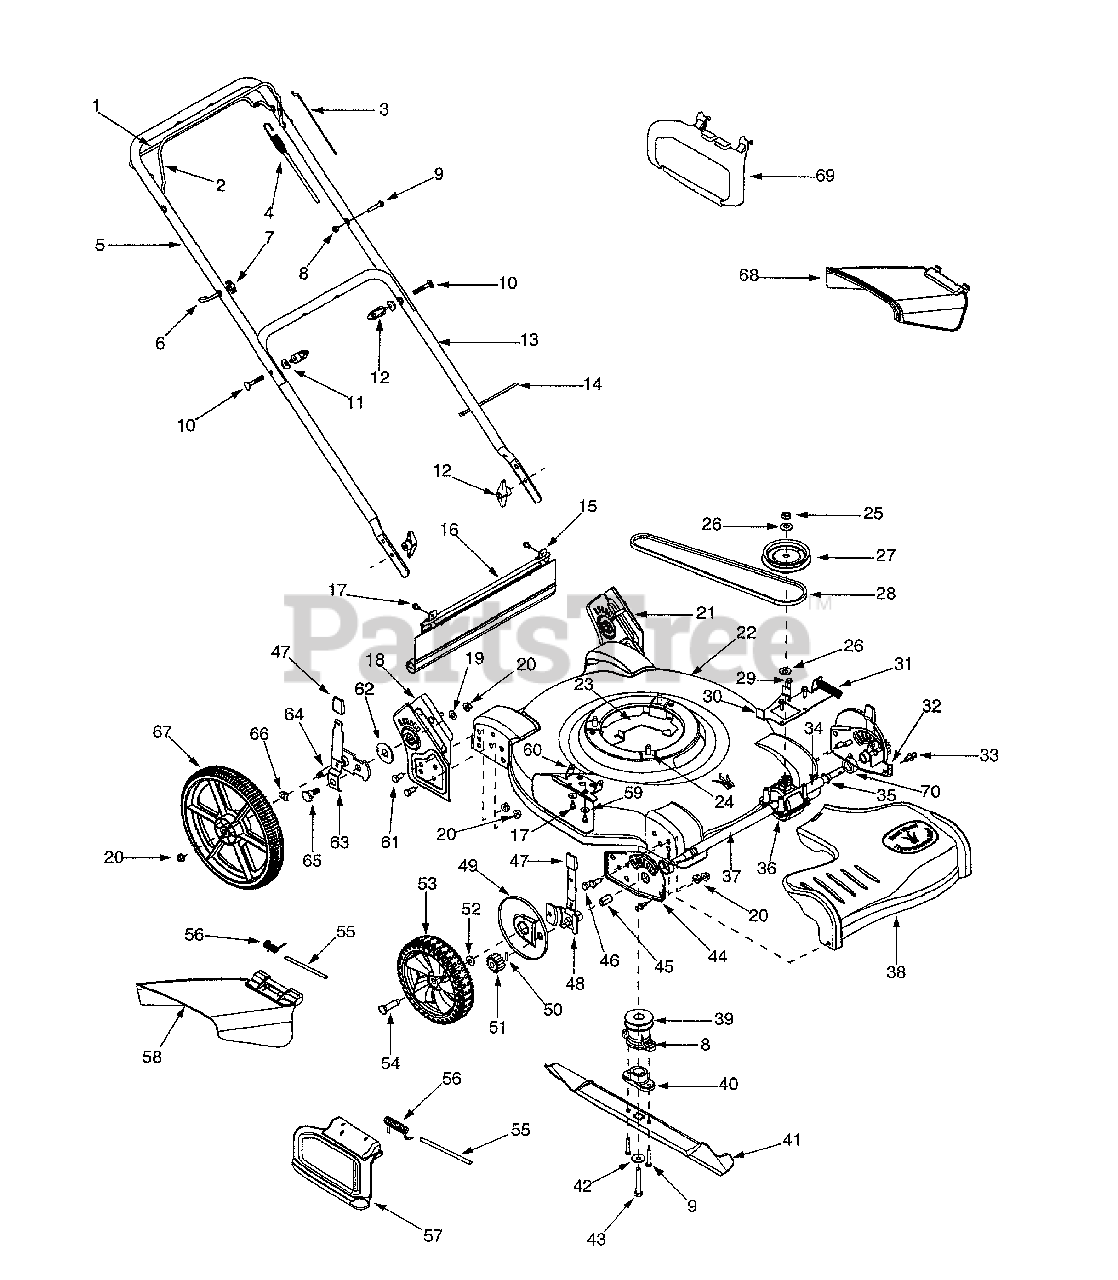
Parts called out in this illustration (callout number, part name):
1	Drive Control Handle
3	Blade Control Cable - B&S
3	Blade Control Cable - Tec
4	Drive Control Cable
6	Eye Bolt
7	Wing Nut 1/4-20
8	Hex Lock Nut 1/4-20
9	Hex Cap Screw 1/4-20 x 1.5
10	Carriage Bolt 5/16-18 x 2.0
11	Shoulder Washer .320 ID x .93 OD
12	Wing Nut
14	Cable Tie
15	Hinge Clip
16	Trail Shield
17	Hex Screw 1/4-14 x .625
19	Flat Washer .406 ID x .812 OD
20	Lock Nut 3/8-16
23	Engine Belt Keeper Bracket
24	Hex Washer Screw 3/8-16 x 1.0
25	Jam Nut 7/16-20
26	Bell Washer .45 ID x 1.00 OD
27	Pulley
28	V-Belt
29	Hex Washer Screw 1/4-20 x .750
30	Transmission Belt Keeper Bracket
31	Compression Spring
33	Rivet
34	Sleeve Spacer .550 ID x 2.5
35	Retainer Ring
36	Transmission Assembly
37	Sleeve Spacer .550 ID x 8.9
38	Transmission Cover
39	Drive Pulley
40	Blade Adapter
41	Blade 22"
41	Mulching Blade 22"
42	Bell Washer .396 ID x 1.140 OD
43	Hex Cap Screw 3/8-24 x 1.5
45	Sleeve Bearing
46	Hex Cap Screw 3/8-16 x .75
47	Adjustment Knob
48	Spring Lever Assembly - LH* (FWD)
48	Spring Lever Assembly - RH* (RWD)
49	Wheel Dust Cover
50	Pin
51	Spur Gear 14T - LH
51	Spur Gear 14T- RH
52	Bell Washer .401 ID x .870 OD
53	Front Wheel Assembly 8 x 1.8
54	Shoulder Screw 3/8
55	Hinge Pin
56	Torsion Spring
57	Mulching Baffle (If Equipped)
58	Side Discharge Assembly
59	Bell Washer .265 ID x .75 OD
60	Chute Hinge
61	Hex Cap Screw 3/8-16 x .75
62	Thrust Bearing .688 ID x 1.938 OD
63	Spring Lever
64	Rear Pivot Arm Assembly
65	Shoulder Screw 3/8-16
66	Spring Washer
67	Rear Wheel Assembly 14 x 1.8
68	Snap Discharge Chute (If Equipped)
69	Snap Mulching Plug (If Equipped)
70	Bearing Spacer
